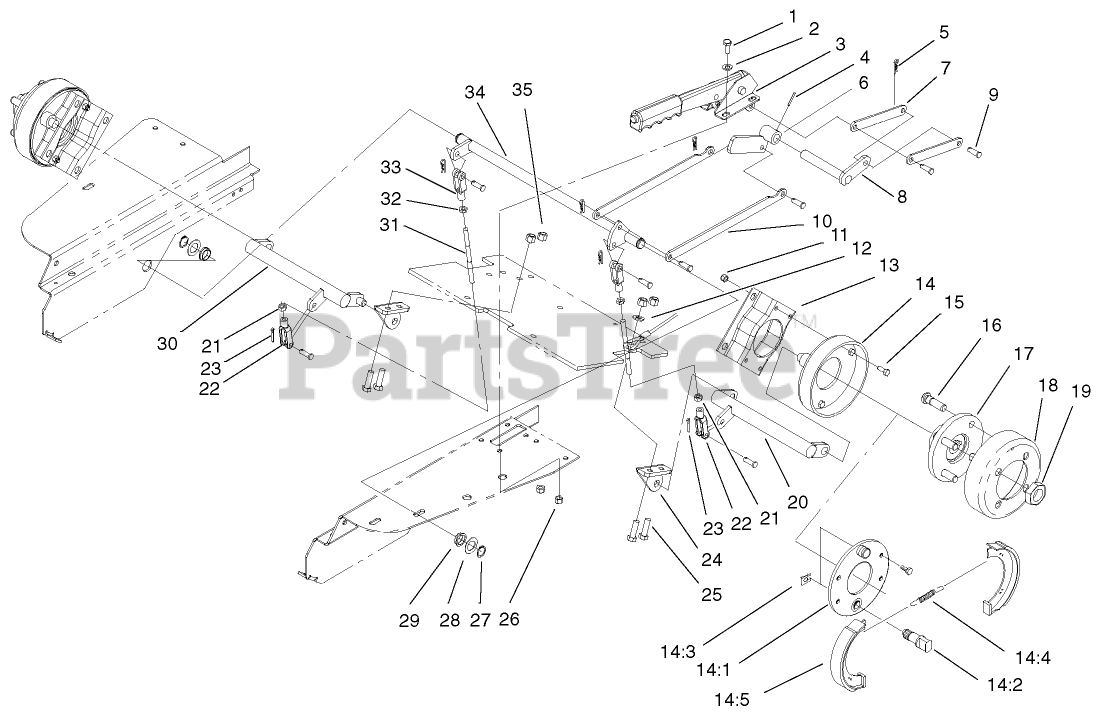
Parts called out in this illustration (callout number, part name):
1	SCREW-HH
2	WASHER-PLAIN
3	LEVER-BRAKE
4	PIN-SPIRAL
5	PIN-COTTER
6	BRAKE HUB ASM
7	LINK-BRAKE
8	TRANSFER SHAFT ASM
9	PIN-CLEVIS
10	LINK - CONNECT
11	NUT-LOCK, NI
12	WASHER-FLAT
13	BRACKET-BRAKE
14	BrakeASM
14:1	PLATE-BACKING
14:2	Cam Shaft
14:3	Clip
14:4	SPRING-RETURN
14:5	SHOE-BRAKE
15	SCREW-HH
16	STUD-DRIVE
17	HUB-WHEEL
18	DRUM-BRAKE
19	NUT-LOCK
20	LH BRAKE LEVER ASM
21	NUT-JAM
22	CLEVIS-ADJUSTABLE
23	PIN-COTTER
24	MOUNT-LEVER, BRAKE, RH
25	SCREW-HH
26	NUT-LOCK, NI
27	Ring-Snap
28	WASHER-FLAT
29	BUSHING
30	RH BRAKE LEVER ASM
31	ROD-BRAKE
32	NUT-JAM
33	YOKE
34	TORSION SHAFT ASM
35	NUT-LOCK, NI
